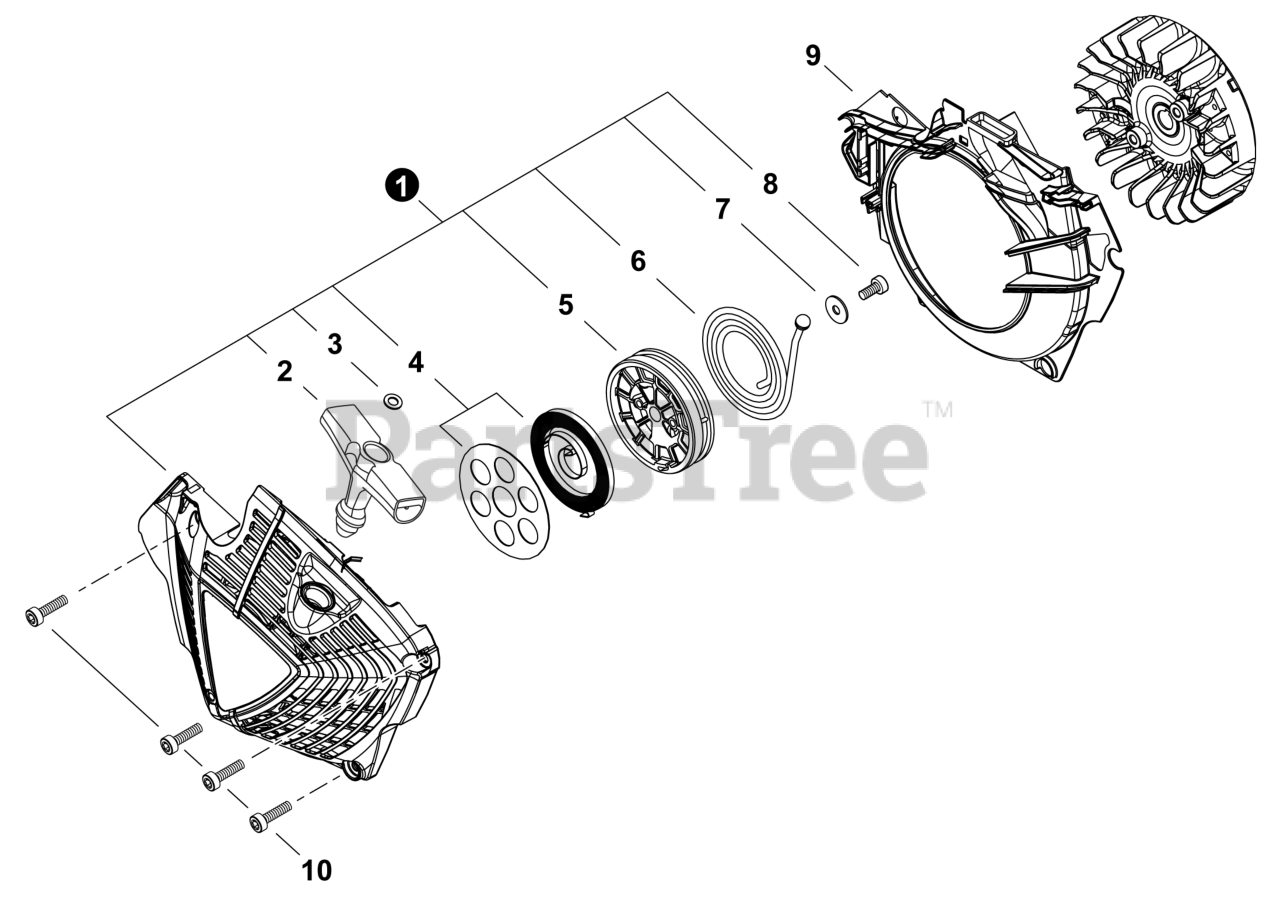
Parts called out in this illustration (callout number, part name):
1	STARTER ASSY
2	GRIP, STARTER
3	WASHER, FLAT 5.5x10x0.8
4	SPRING KIT, RECOIL
5	REEL, ROPE
7	WASHER 5.2x16x1.0
8	BOLT, TORX 5x10
9	COVER, FAN
10	BOLT, TORX 5x20
